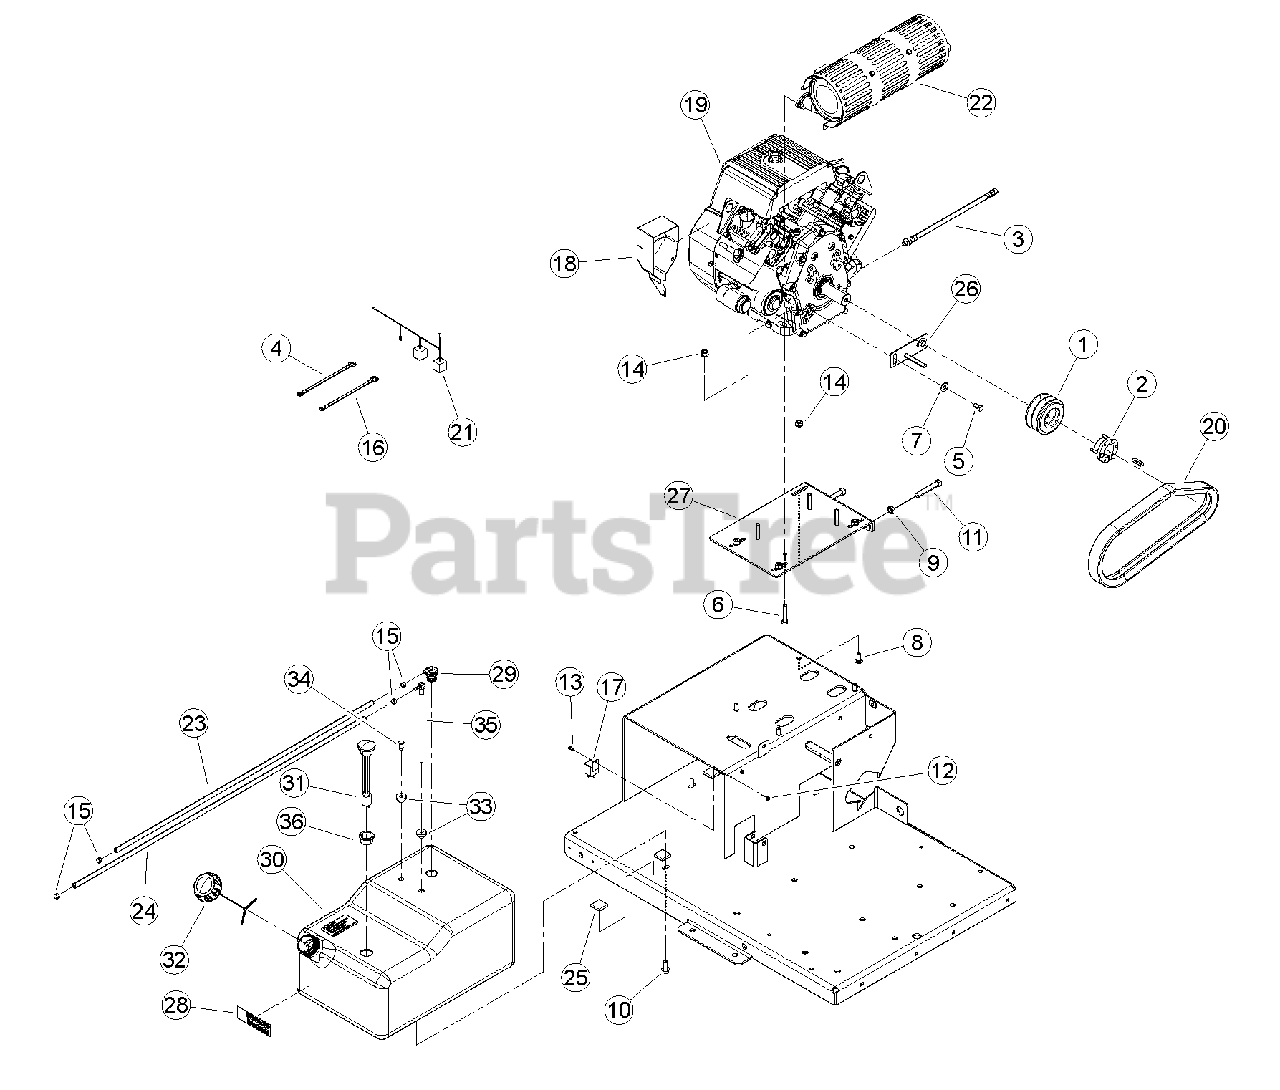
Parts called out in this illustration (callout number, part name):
1	SHEAVE, 2B3.6 SH QD
2	BUSHING, SH 1-7/16
3	HOSE ASSEMBLY, CRANKCASE DRAIN
4	CABLE, 24" NEG
5	BOLT, 3/8 X 3/4 GR5 HEX CAPSCREW ZP
6	BOLT, 3/8 X 2 GR5 HEX CAPSCREW ZP
7	WASHER, 3/8" FLAT ZP
8	BOLT, 3/8 X 1" CRG GR5 NC ZP
9	NUT, 1/2 NC ZP JAM
10	BOLT, 3/8 X 1 FLANGE NC
11	SETSCREW, 1/2 X 3 SQ HD 1/2 DOG PT
12	NUT, 10/24 NYLOCK TYPE NM ZP
13	SCREW, MCH 10-24 X 1/2" PAN HD PH ZP
14	NUT, 3/8-16 NYLOCK-FLANGE
15	CLAMP, 15/32 SPRING
16	CABLE, 33" POS
17	RELAY, 12V SPDT W/ FLANGE
18	CONTROL, SUBARU V-TWIN IGNITION
20	BELT, 2RB40
21	HARNESS, CARB SAFETY RELAY
22	MUFFLER, SUBARU OIL FILTER SIDE
23	HOSE, 38" FUEL LINE
24	HOSE, 43" FUEL LINE
25	PAD, FOAM FUEL TANK DAMPER
26	WELDMENT, BELT GUIDE
27	WELDMENT, ENGINE ADJUSTER
28	DECAL, UNLEADED GASOLINE
29	VALVE, ROLL OVER
30	TANK, ROTOMOLDED FUEL
31	GAUGE, FUEL LEVEL KELCH 100
32	CAP, NON-VENTED EPA/CARB APPROVED
33	GROMMET, TANK FITTING
34	PLUG, TANK VENT
35	FITTING, TANK FUEL PICK-UP TUBE
36	GROMMET, KELCH 100 GAUGE
